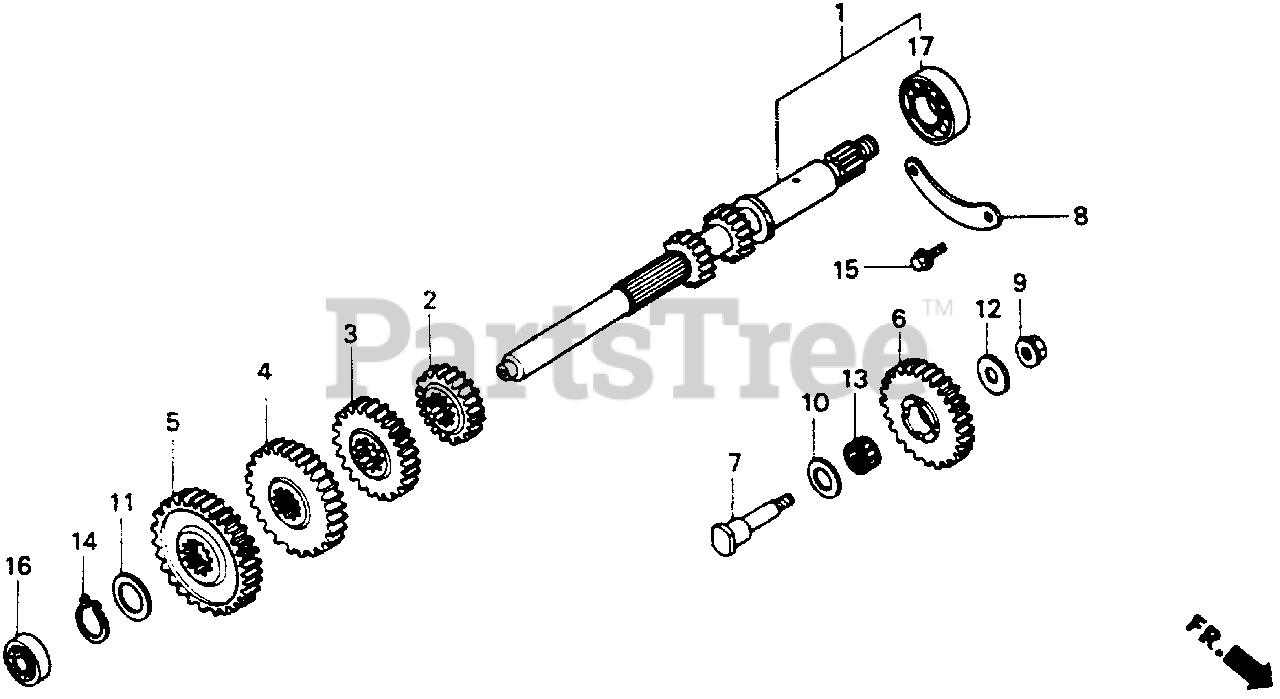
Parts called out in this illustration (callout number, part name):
1	MAINSHAFT (NOT AVAILABLE)
2	GEAR, MAINSHAFT SECOND (18T)
3	GEAR, MAINSHAFT THIRD (24T)
4	GEAR, MAINSHAFT FOURTH (27T)
5	GEAR, MAINSHAFT FIFTH (29T)
6	GEAR, REVERSE IDLE (27T)
7	SHAFT, REVERSE IDLE
8	HOLDER, BEARING
9	NUT, SELF-LOCK (10MM)
10	WASHER, THRUST (15MM)
11	WASHER, THRUST (16MM)
12	WASHER, PLAIN (11MM)
13	BEARING, NEEDLE
14	CIRCLIP (OUTER) (16MM)
15	BOLT, FLANGE (6X16)
16	BEARING, RADIAL BALL (6001)
17	BEARING, RADIAL BALL (6004)
